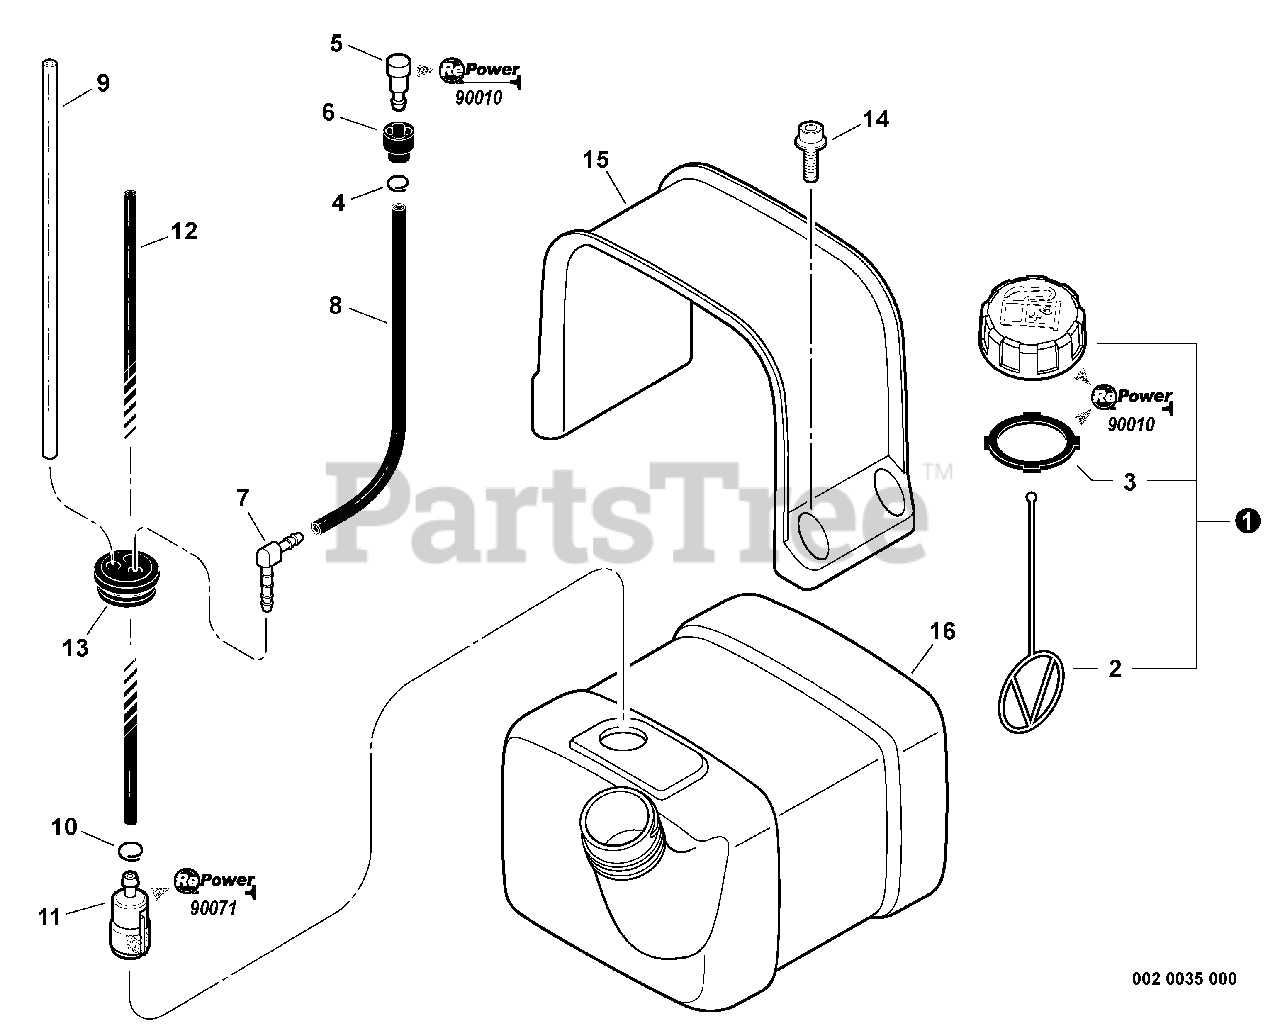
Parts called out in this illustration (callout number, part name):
1	CAP ASSY - ORANGE
2	CONNECTOR, CAP
3	GASKET, CAP
4	CLIP - 6.5
5	VENT, FUEL TANK
6	COVER, VENT
7	CONNECTOR, PIPE
8	PIPE - 3X6X145 -- BLACK
9	PIPE - 3X6X145 -- CLEAR
10	CLIP - 6.5
11	FILTER, FUEL
12	PIPE - 3X6X230 -- BLACK
13	GROMMET
14	SCREW - 5X16
15	COVER, FUEL TANK
16	TANK, FUEL
17	Repower CAP AND VENT KIT
18	RePower TUNE-UP KIT
